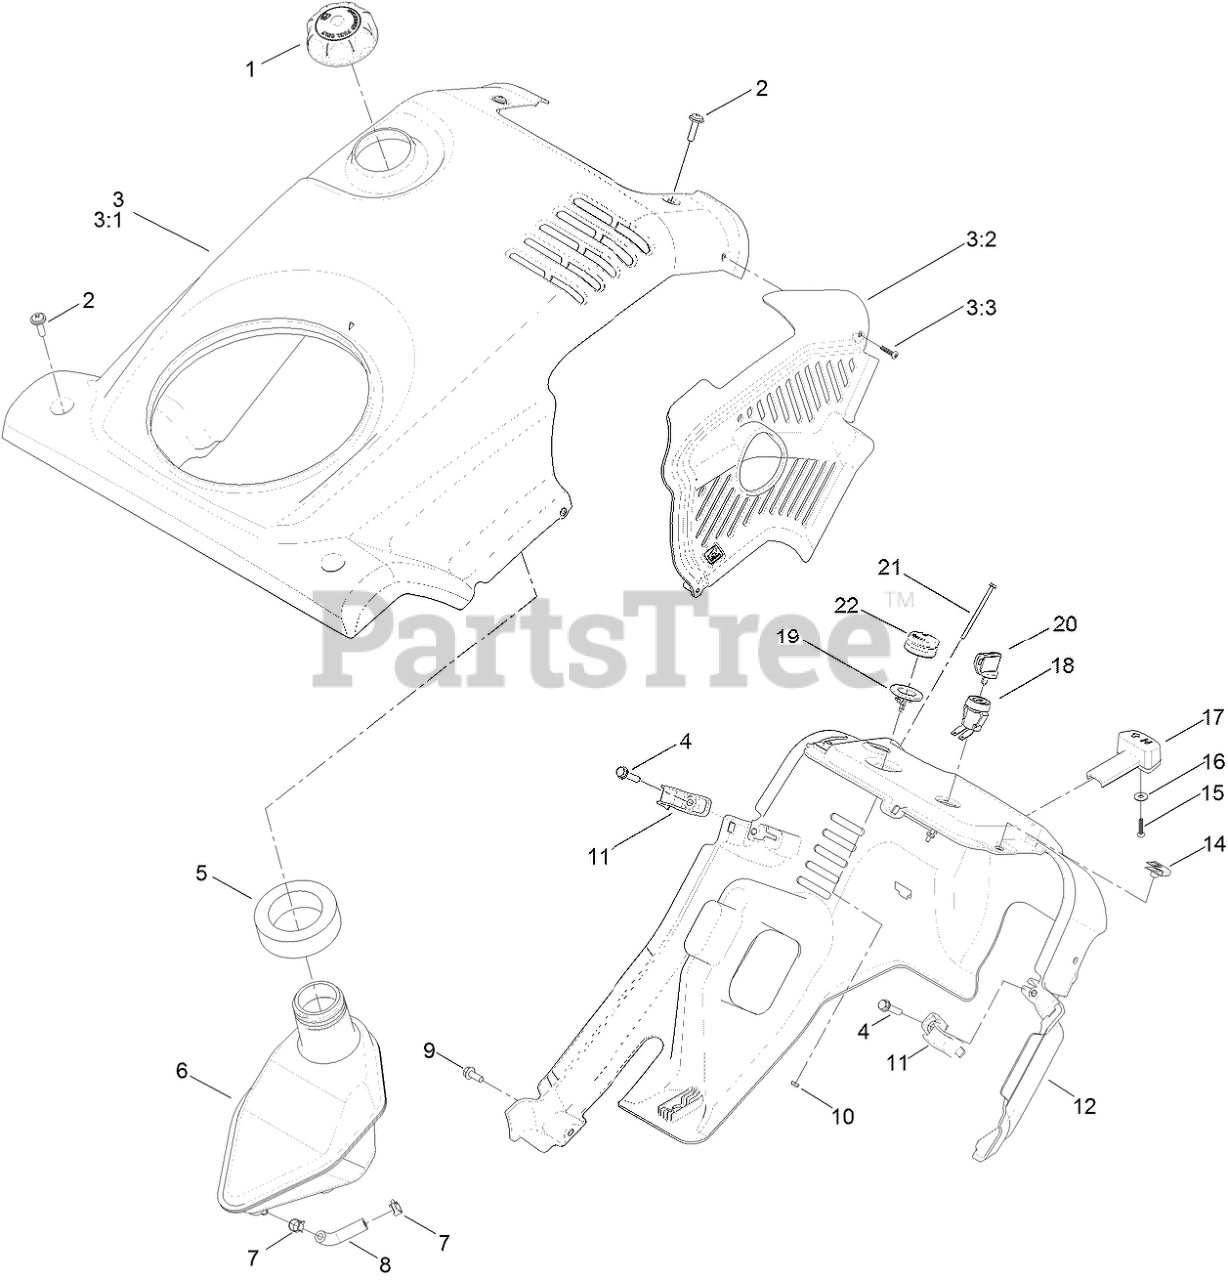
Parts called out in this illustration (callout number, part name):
1	CAP-GAS
2	SCREW-PPH
3	SHROUD ASM
3:1	SHROUD
3:2	BAFFLE-EXHAUST
3:3	SCREW-PPH
4	SCREW-PLASTITE
5	SEAL-TANK
6	TANK-FUEL, GAS
7	CLAMP-HOSE
8	HOSE-FUEL
9	SCREW-HWH
10	NUT-HEX
11	CLIP-SHROUD
12	SHROUD-LOWER
15	SCREW-PPH
16	WASHER-PLAIN
17	KNOB-CHOKE
18	SWITCH
19	BODY-PRIMER
20	KEY-IGNITION
21	SCREW-HWH
22	BULB-PRIMER
